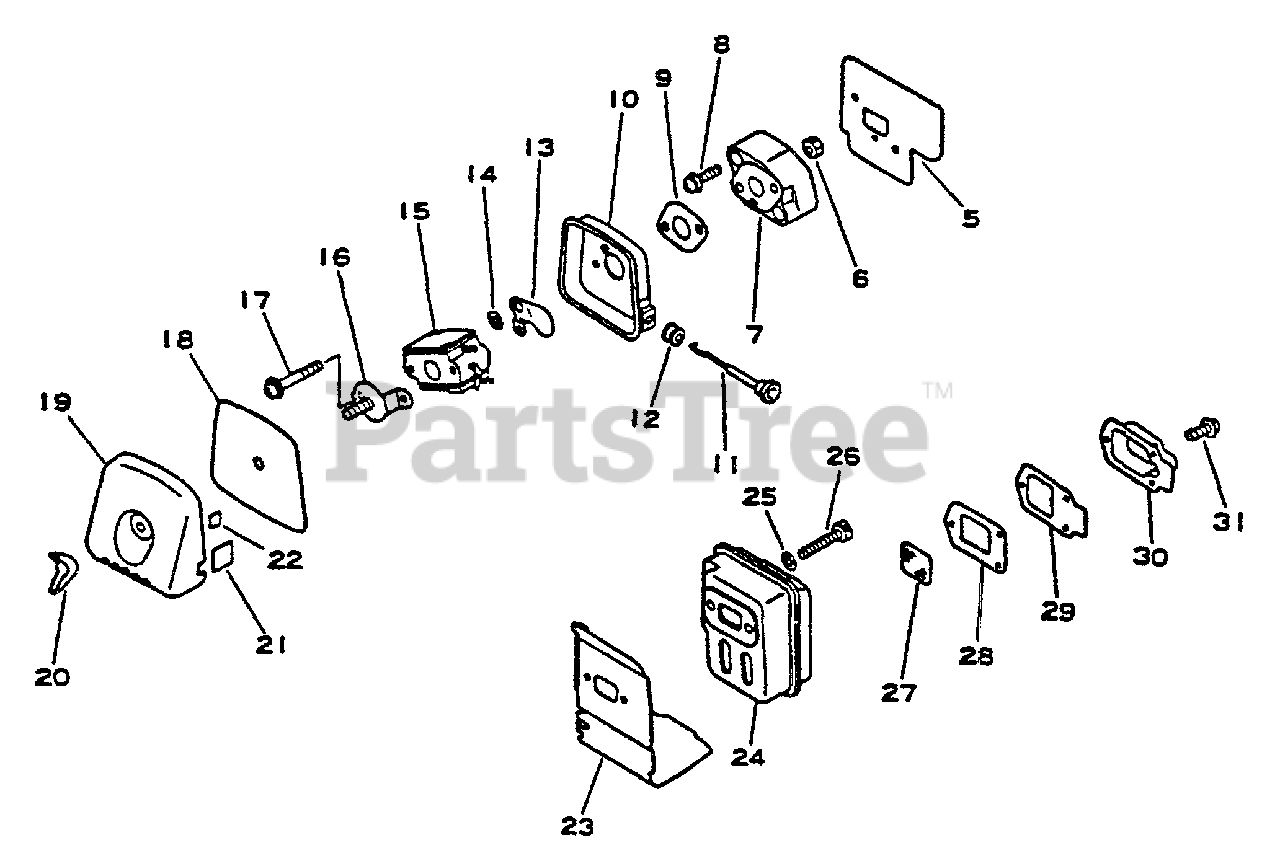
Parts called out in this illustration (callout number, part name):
5	GASKET, INTAKE
7	INSULATOR, INTAKE
8	SCREW - 5X22
9	GASKET, INTAKE
10	CASE, AIR FILTER
11	ROD, CHOKE
13	SHUTTER, CHOKE
14	WASHER - 5
15	CARBURETOR
16	PLATE, PREVENT
17	SCREW - 5X57
18	FILTER, AIR
19	COVER, AIR FILTER
20	WINGNUT - 6
21	LABEL - CAUTION
22	LABEL - CHOKE
23	SHIELD, EXHAUST
25	WASHER - 5
26	SCREW - 5X55
27	SCREEN, SPARK ARRESTOR
28	GASKET, EXHAUST
29	GASKET, EXHAUST - INNER
30	GUIDE, EXHAUST - INNER
31	SCREW - 4X10
